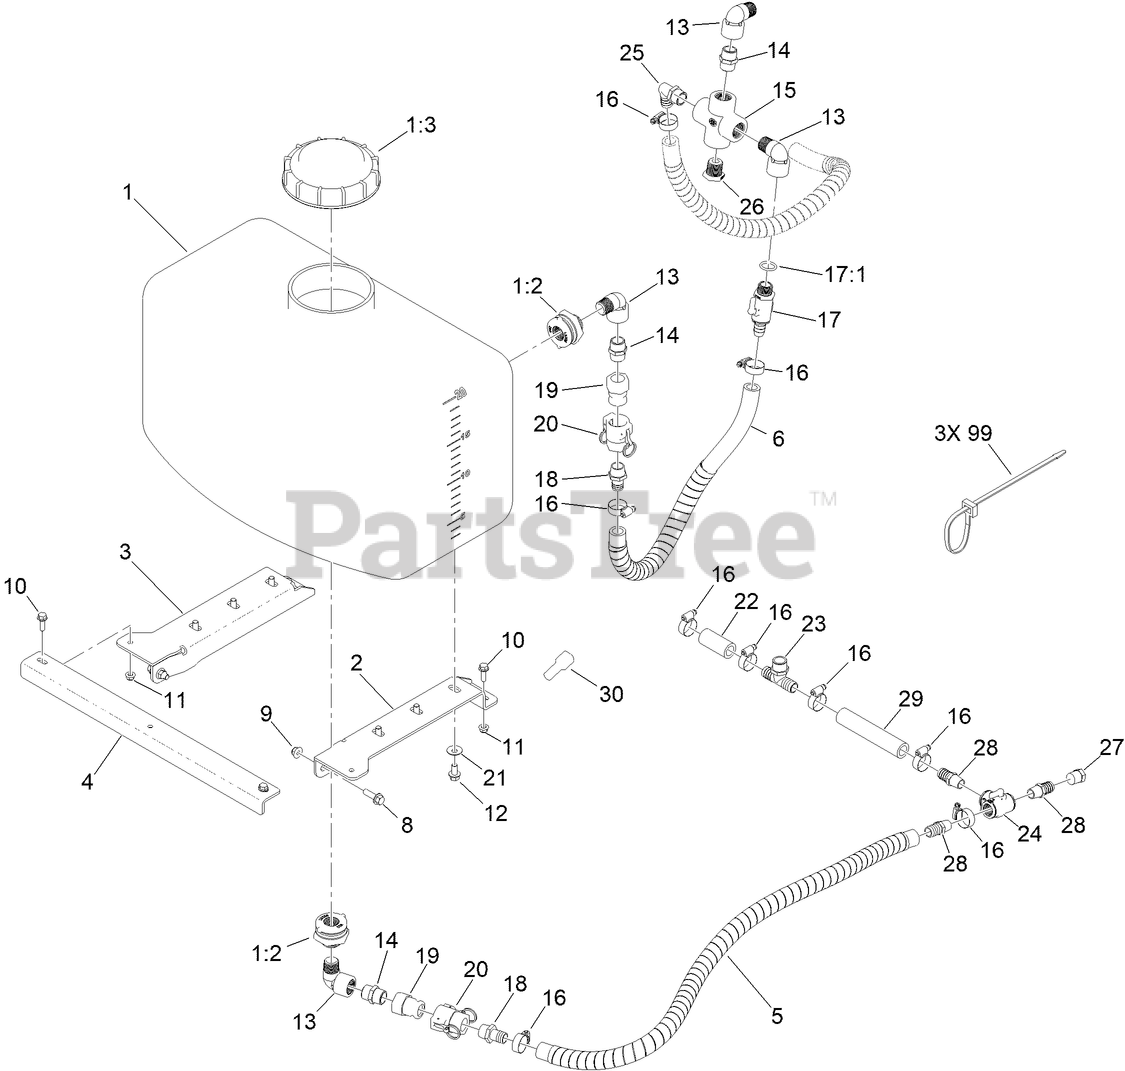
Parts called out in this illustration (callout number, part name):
1	ASM-TANK, 20 GAL
1:2	FITTING-BULKHEAD
1:3	CAP-TANK, SPRAY
2	MOUNT-TANK, LT
3	MOUNT-TANK, RT
4	SUPPORT-TANK, FRONT
5	HOSE-SPRAY, WRAPPED
6	HOSE-SPRAY, WRAPPED
8	SCREW-HHF
9	NUT-HEX FLANGE
10	SCREW-HHF
11	NUT-HEX FLANGE
12	SCREW-HHF
13	ELBOW-90 DEG
14	FITTING-NIPPLE
15	FITTING-CROSS
16	CLAMP-HOSE
17:1	O-RING, -213
18	HOSEBARB
19	ADAPTER-MALE
20	COUPLER-FEMALE
21	WASHER-SPRING
22	HOSE-SPRAY
23	FITTING-TEE
24	Carburetor, Complete (Incl. Ref. #33)
25	FITTING-ELBOW, 90
26	FITTING-PLUG
27	PLUG-VALVE
28	FITING-STRAIGHT
29	HOSE-SPRAY
30	BOOT-RECEPTACLE
99	TIE-CABLE
